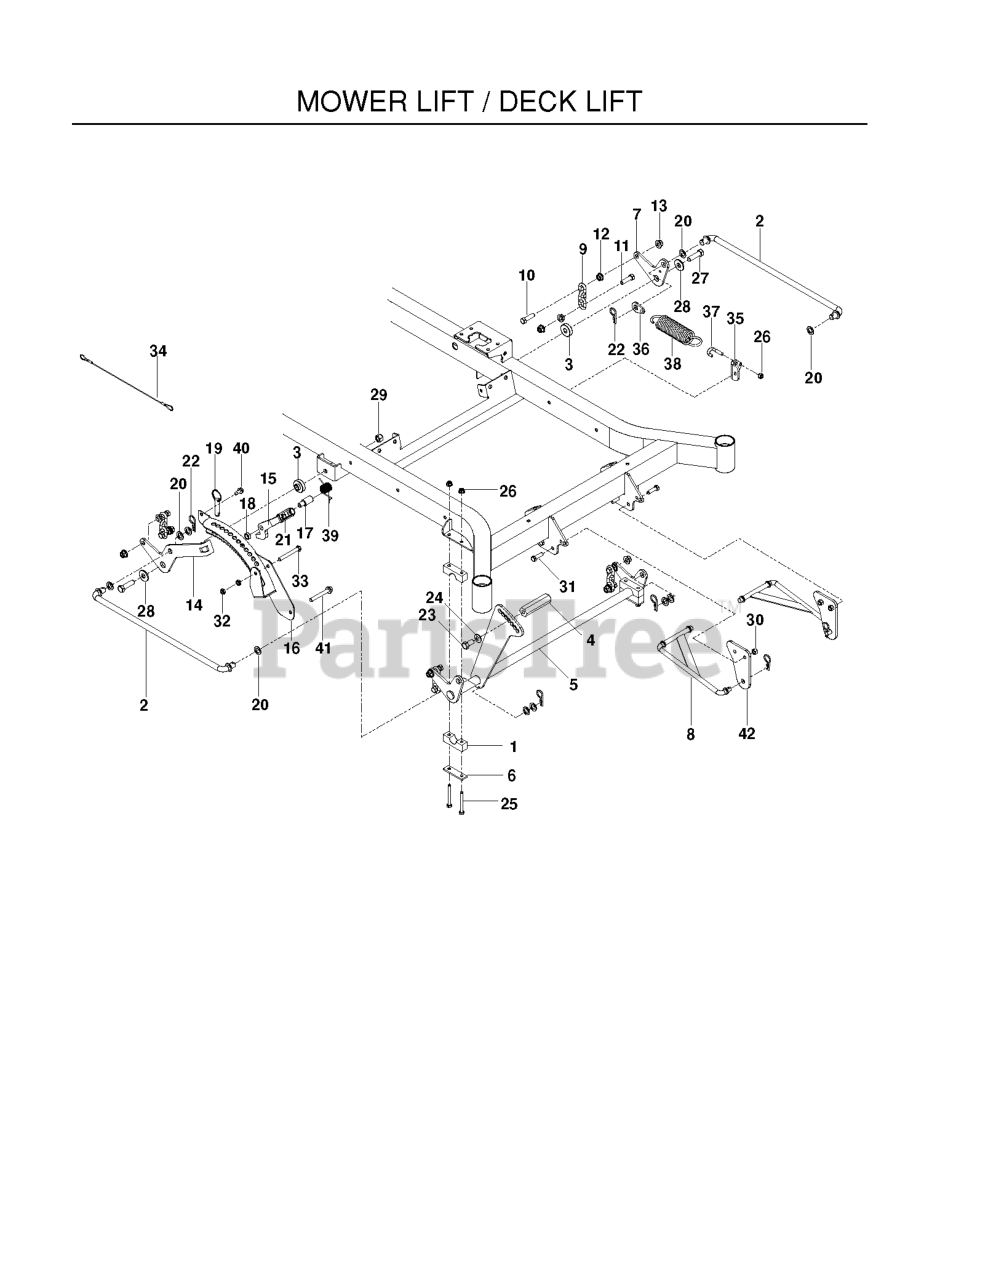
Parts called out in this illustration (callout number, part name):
1	PILLOW BLOCK
2	CROSS LINK
3	IDLER SPACER
4	PEDAL, FOOT, HEX
5	SHAFT, FT, LIFT - BLK
6	REINFORCEMENT BAR
7	BELLCRANK, RR, LIFT
8	STRUT LINKAGE
9	LIFT CHAIN - 3 LINK
10	HCS 7/16C X 1 1/2
11	HCS 7/16 - 14 X 1 3/4
12	NUT 7/16C WHIZ
13	NUT 7/16-14 HEX WHIZ LK
14	BELLCRANK, RR, RT
15	LATCH, TRANSPORT
16	HEIGHT, ADJUST, DECK
17	PIVOT, LATCH, TRANSPORT
18	SPACER, .3
19	PIN, 1/2 X 1 1/2, DETENT RING
20	BUSHING
21	GRIP, TRANSPORT-RELEASE
22	PIN, COTTER 1 3/4
23	HHCS 1/2-13 X 1
24	WASHER, 7/16 DISC SPRING
25	HCS 5/16C X 2-3/4
26	5/16-18 NYLOC FLANGE NUT
27	HCS 1/2-13 X 1 3/4 GR 8
28	WASH USS FLAT 1/2
29	NUT 1/2-13 HEX NYLOC ZD
30	NUT 3/8-16 NYLOC
31	HCS 3/8C X 1 1/4 GR5
32	NUT HEX 3/8-16 NYLON, THIN
33	HCS 3/8C X 3
35	MOUNT, SPRING
36	TAB, SPRING
37	J-BOLT
39	SPRING, TORSION
40	BOLT 5/16-18 X 3/4
41	HHFS 3/8-16 X 2 3/4
42	MOUNT, STRUT
